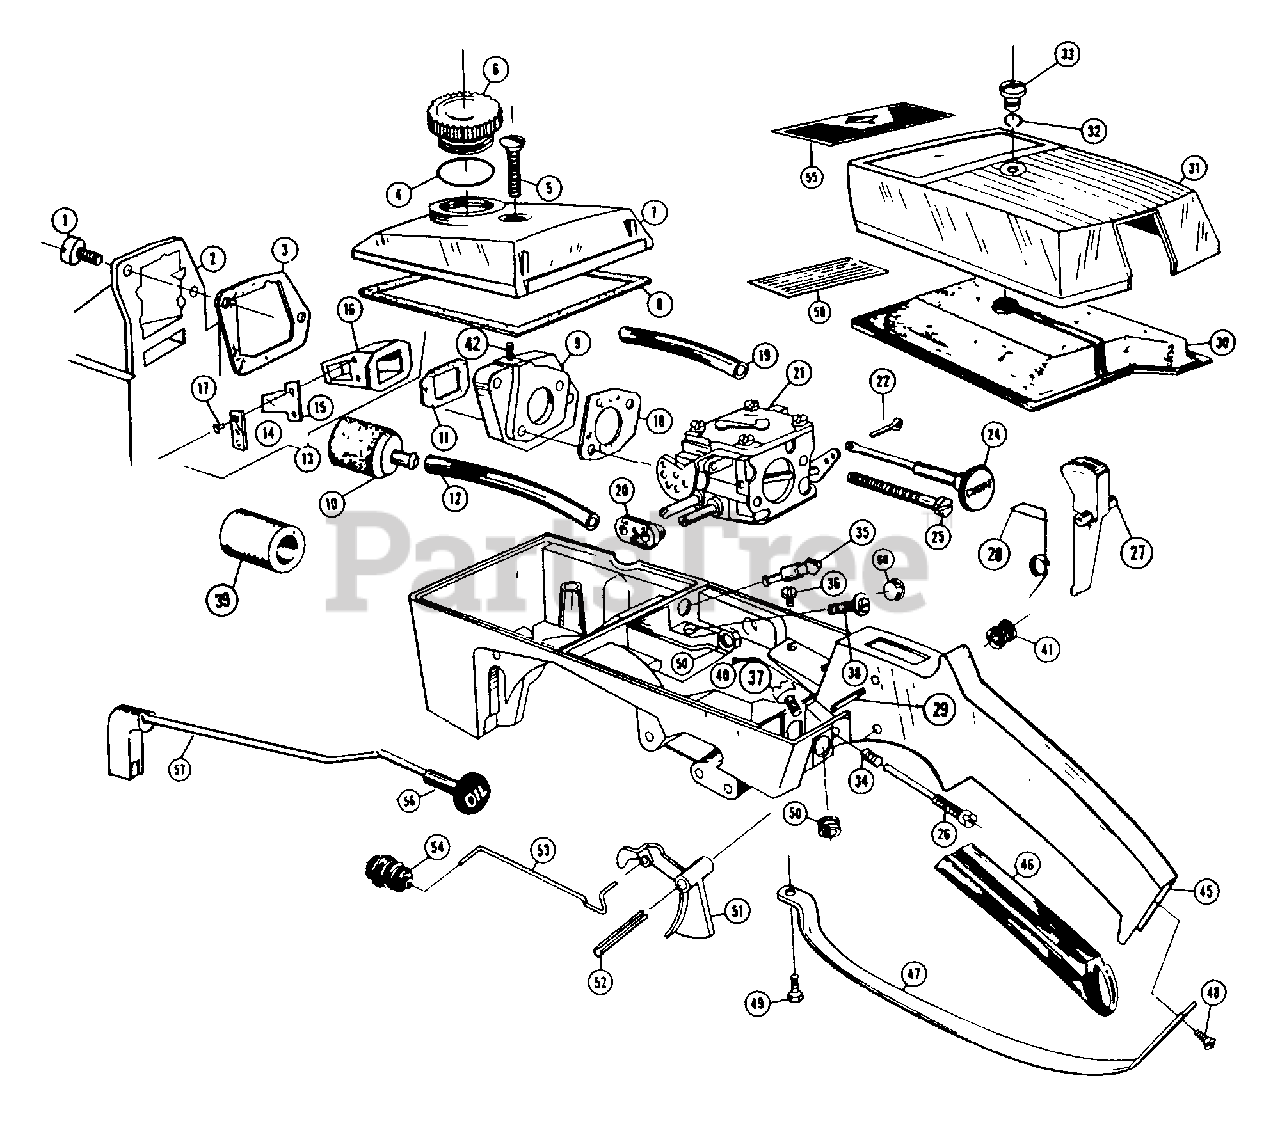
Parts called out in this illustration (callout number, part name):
2	Crankcase
3	Gasket - Carburetor - Adapter to C/Case
4	O'Ring - Gas Cap Ass'y.
5	Screw - Gas Tank Cover
6	Gas Cap Assembly
7	Cover - Fuel Tank
8	Gasket - Fuel Tank
9	Adapter Assembly
10	Fuel Pick-Up
11	Gasket - Reed Valve
12	Fuel Line Pick-Up
13	Reed Valve -
14	Stop Reed
16	Block - Reed
17	Screw 4-40 x 1/8
18	Gasket -Carburetor to Adapter
19	Line -Fuel to Carburetor
20	-Grommet -Carb. Screw
21	Carburetor
22	Cotter Pin - 3/32 x 1/2
23	Choke Rod
25	Screw- Carburetor Mount
26	Screw -Idle
27	Button-Throttle lock
28	Roll Pin -Throttle Lock
29	Spring - Throttle Lock Button
30	Filter - Air
31	Cover - Air Filter
32	Ring - Retainer
33	Nut - Filter Cover
34	Spring -Idle Screw
35	Fitting - Fuel Tank
37	Screw - Cyl. Shield to Tank
38	Screw - Tank and Handle to C/Case
39	Filter-Fuel
40	Cotter Pin-C/Case Drain
41	Grommet
42	Stud - Adapter
45	Tank & Handle Ass'y
46	Grip - Handle
47	Handle Brace - Rear
48	Screw - Brace Mount
49	Screw -Brace Mount
50	Nyliner
52	Roll Pin
53	Rod - Throttle
54	Boot - Throttle
55	Decal
56	Button - Oiler
57	Push Rod and Bumper
58	Decal - Instruction
60	Plug Tank & Handle Ass'y
